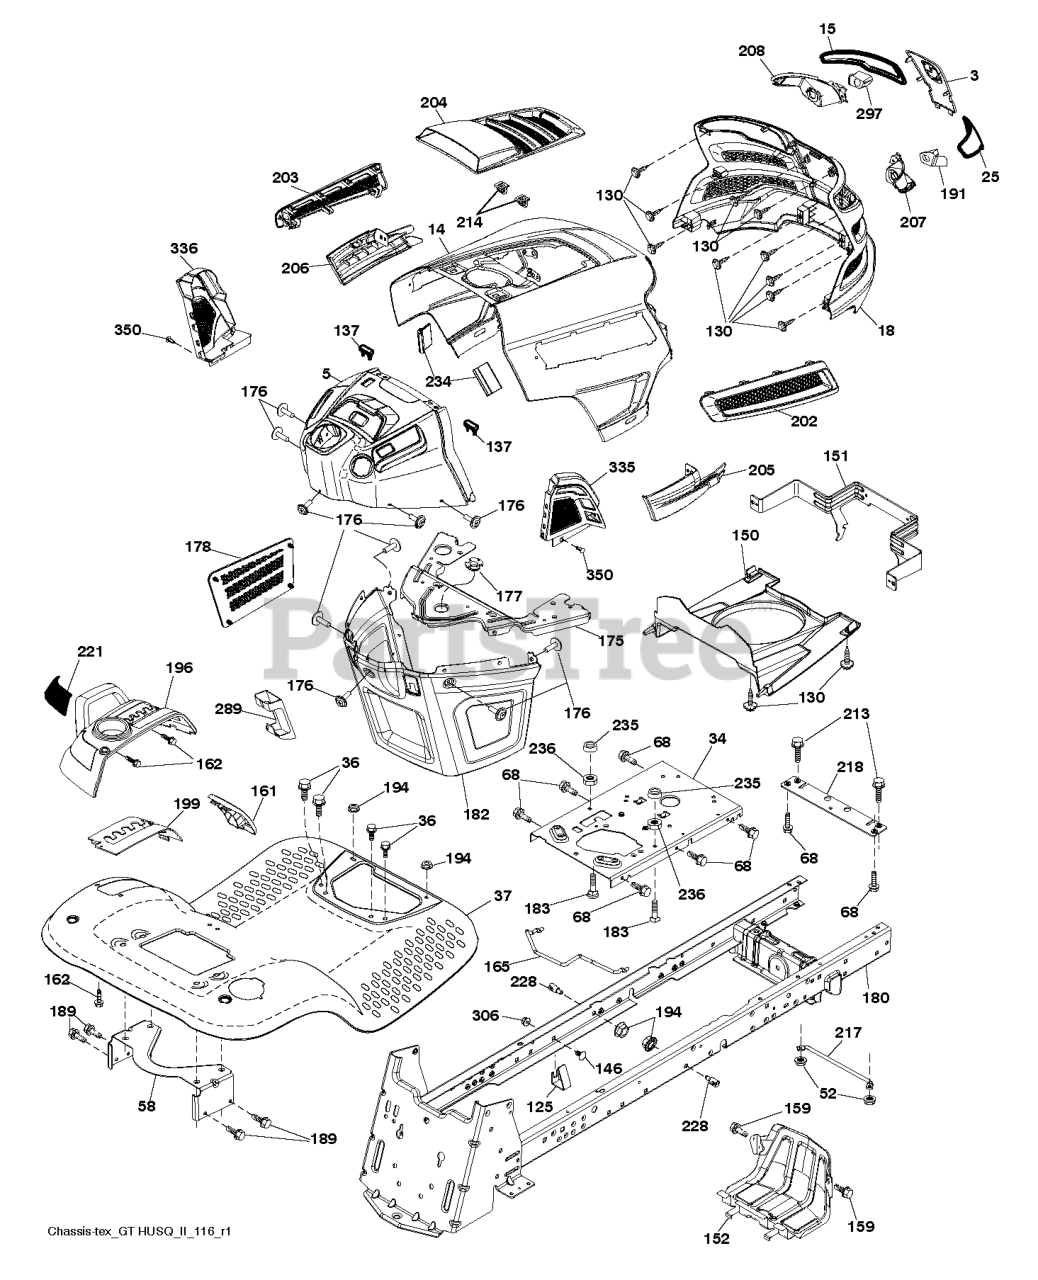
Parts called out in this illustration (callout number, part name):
3	APPLIQUE.SUBASM.GT.HUSQ.II
5	DASH.UPP.GT2.SM.PTO.MC.HR.GREY
14	HOOD.ASM.HUSQVARNA.GT.TEX.ORAN
15	LENS.HEADLIGHT.LH.GTII.2011
18	GRILLE.SUBASM.GT.HUSQ.II
25	LENS.HEADLIGHT.RH.GTII.2011
34	PLATE.ENGINE.WELDED.CHASSIS
36	SCREW 5/16"
37	FENDER.PNT.TX.GT.CH/FW/DL.HUSQ
52	LOCKNUT
58	BRKT.SUPPORT.FNDR/TANK
68	Screw 5/16-18 x 1/2 Hex, Self Tapping 5/16-18 x 1/2
125	CLIP.FUEL.LINE
130	SCREW.#10 X 0.750.BOS
137	BUMPER DASH
146	BOLT.RDHD.SHT.SQNK.3/8-16X5/8
150	AIR.DUCT.GTV.BLACK
151	BRACKET.PIVOT.HOOD.GT.HUSQ.II
152	SHIELD.BROWNING.PNT.GT.V2
159	SCREW, 3/8-16X3/4
161	CONSOLE.WINDOW.FUEL.HUSQ.GT
162	SCREW.HI-LO.CONSOLE
165	SUPPORT.TANK.REAR.W/TEX
175	PLATE.CROSSMEMBER.HUSQ
176	SCREW.#10-24X5/8.RN.QU
177	BUSHING, STEERING
178	CARGO.ASM.NET.TXGT.W/C
180	CHASSIS.GT.SLOPED.DRAWBAR.
182	DASH.LOWER.COMMON.12V.ADAPTOR
183	BOLT.5/16-18X1-1/4 FULL THD
189	SCREW
191	INSERT.REFLECTIVE.RH.HUSQ.GTII
194	NUT LOCK HEX FLANGE 5/16-18
196	SUBASM.CONSOLE.HUSQ.GT.DECKLFT
199	PLATE.DECK.LIFT.HUSQVARNA.GT
202	VENT.SIDE.RH.GT.HUSQ.II.
203	VENT.SIDE.LH.GT.HUSQ.II.498
204	VENT.TOP.ASM.HUSQ.GT2
205	SIDE.TRIM.RH.GT.HUSQ.II
206	SIDE.TRIM.LH.GT.HUSQ.II.GRAY
207	BEZEL LIGHT.RH.GT.II.MYLAR
208	BEZEL LIGHT.LH.GT.II.MYLAR
213	BOLT
214	CLIP.RETAINER.TINNER.
217	ROD.PIVOT.HOOD
218	X-PIECE.HOOD.STOP.NON/
221	REFLECTOR.LH.TEX GT HU
228	STUD.FASTNER.W/ANTI-ROTATE
234	BUMPER.HOOD.TEX.HUSQVARNA
235	SPACER FENDER
236	NUT.CENTERLOCK.5/16-
289	PLUG.N/CRUISE.COMMON.YT/GT.BLK
297	INSERT.REFLECTIVE.LH.HUSQ.GTII
306	NUT LOCK FLG 3/8-16 UNC
335	COVER.LOWER.DASH.RH.BLACK
336	COVER-LH.LOWER.DASH.GT2.BLACK
350	CLIP.X-MAS.TREE
